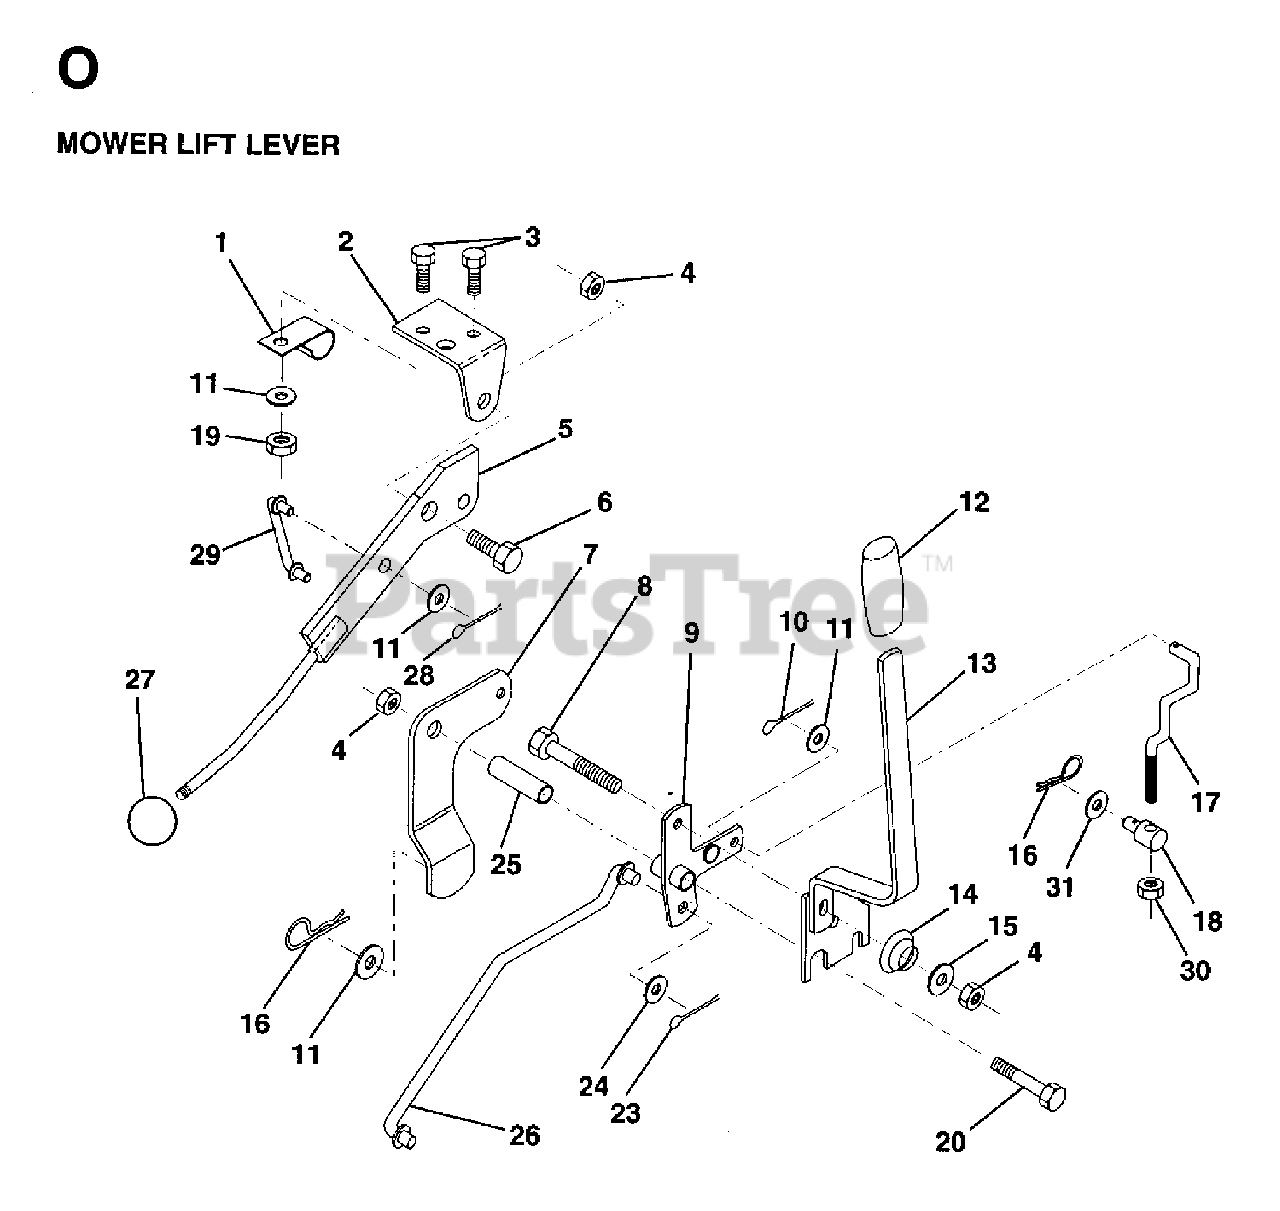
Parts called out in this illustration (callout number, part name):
1	CLIP,INSULATOR
2	BRKT CLUTCH
4	LOCKNUT
6	BOLT, SHOULDER LT
7	ASSEMBLY MOWER CLUTCH ARM
9	BELLCRANK,LIFT
10	COTTER PIN
12	GRIP HANDLE
13	LIFT HANDLE ASSY
14	SPRING COMPRESSIO
15	WASHER T
16	SPRING TI
17	LINK LIFT FRT
19	NUT.CROWNLOCK.1/4
23	PIN COTTER
24	WASHER GT
25	TUBE SPACER
27	KNOB
28	COTTER PIN
29	LINK MOWER CLUTCH
30	NUT
S	CLUTCH LEVER
